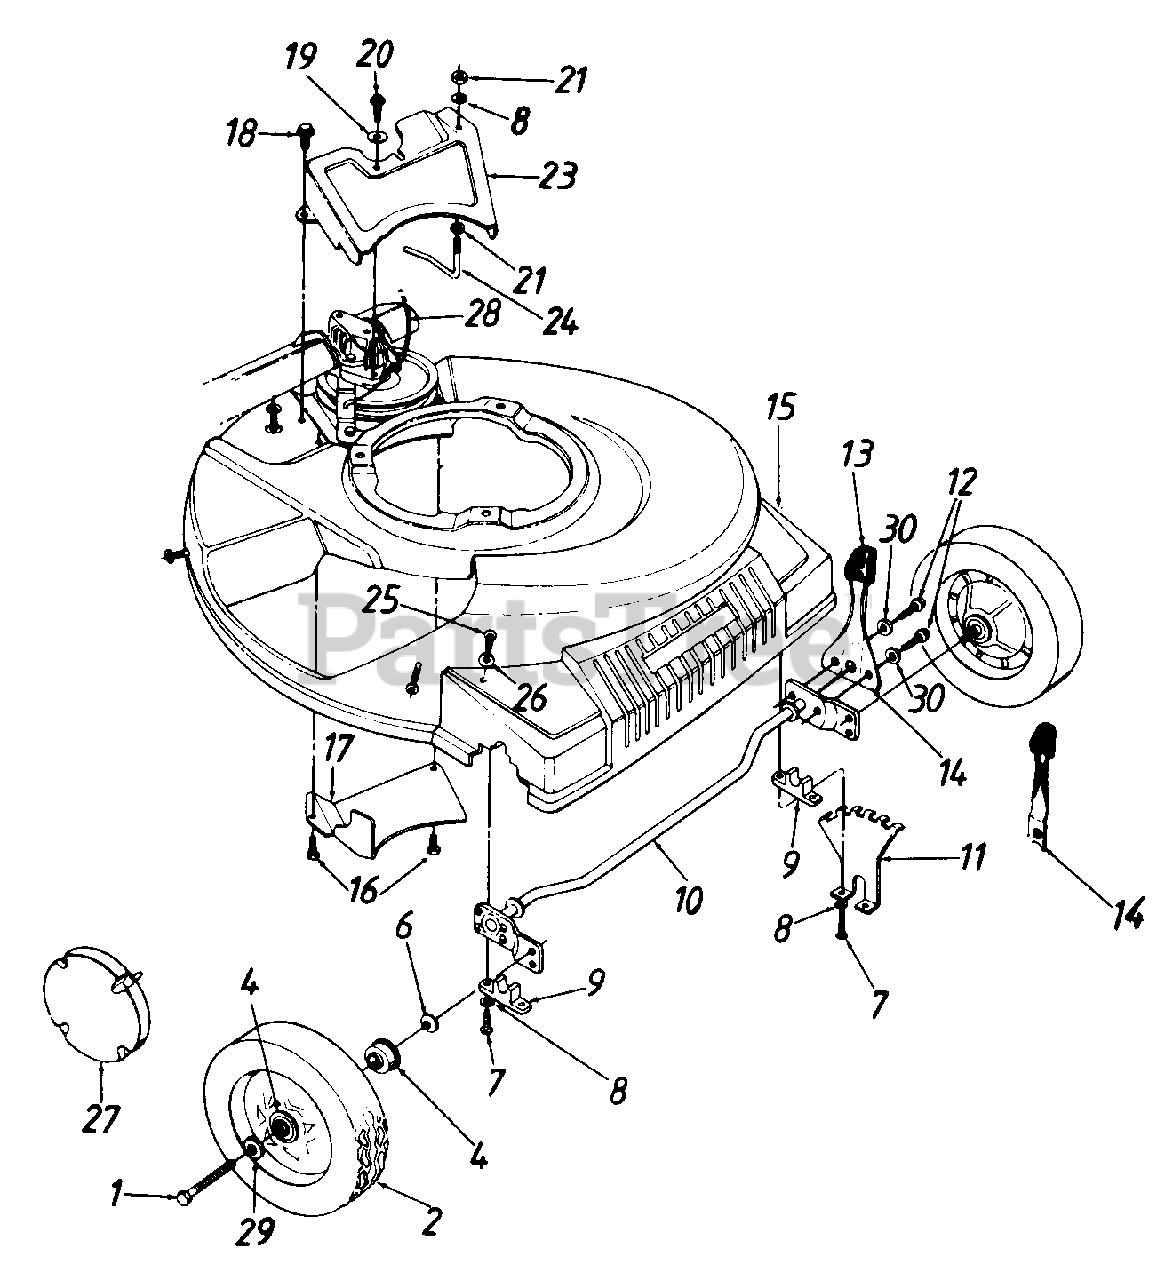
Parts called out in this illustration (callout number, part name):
1	Front Axle Bolt
2	Wheel Ass'y. Comp. 8 x 2"
4	Flange Ball Brg. .501" I.D.
6	Bell-Wash. .380" I.D. x .88
7	Hex B-Tap Scr. 1/4-20
8	L-Wash. 1/4" I.D.
9	Block Bushing
10	Axle Ass'y.
12	Hex TT-Tap Scr. 1/4-20 x .5"
13	Knob
14	Spring Lever (With 1 hole)
15	Plastic Front End
16	Hex B-TaD Scr. 1/4" x .38"
19	Bell-Wash. .265" I.D. x .75"
20	Hex Wash. Hd. B-Tap Scr. 1/4 X .62"
21	Hex Nut 1/4-20 Thd.
25	Truss B-Tap Scr. 5/16 x .75"
26	Bell-Wash. .345" I.D. x .88" O.D.
27	Hub Cap
28	S.P. Cable 50" Lg.
29	Wave Wash. .53" I.D. x .78"
30	External L-Wash. 1/4" I.D.
